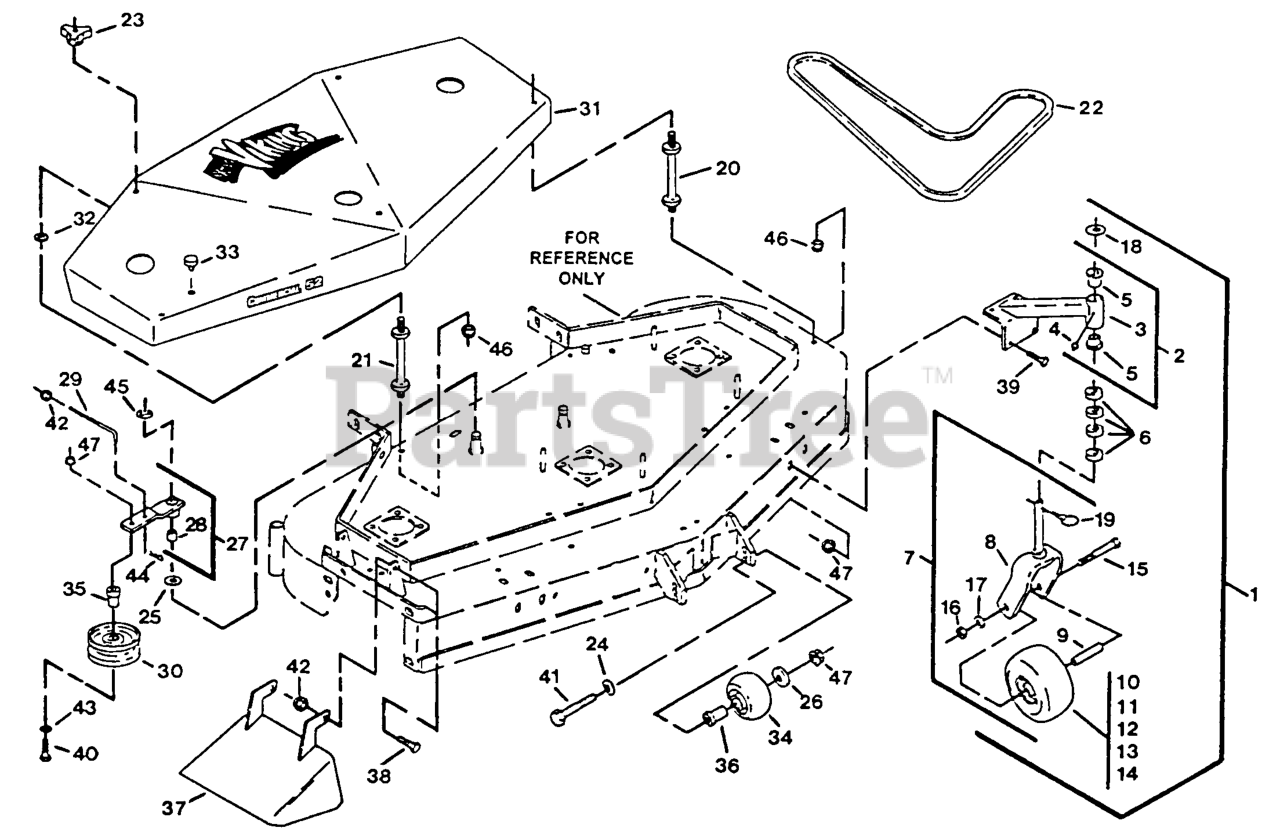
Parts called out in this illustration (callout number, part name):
1	CASTER/MOUNT ASM
2	SUPPORT ASM
5	BEARING-FLANGED
6	SPACER-CASTER
13	BEARING
14	BUSHING
18	WASHER-FLAT
20	STUD-SHIELD, BELT (SHORT)
21	STUD-SHIELD, BELT (LONG)
23	KNOB-3 PRONG
25	WASHER-SPINDLE
27	ARM WLDMNT W/BUSHING
28	BEARING,POWDERED METAL
29	LINKAGE
30	IDLER,PULLEY
34	ROLLER-SCALP, ANTI
35	BUSHING-IDLER
36	BUSHING-ROLLER
37	WLD,CHUTE DISCHARGE
44	PIN-COTTER
